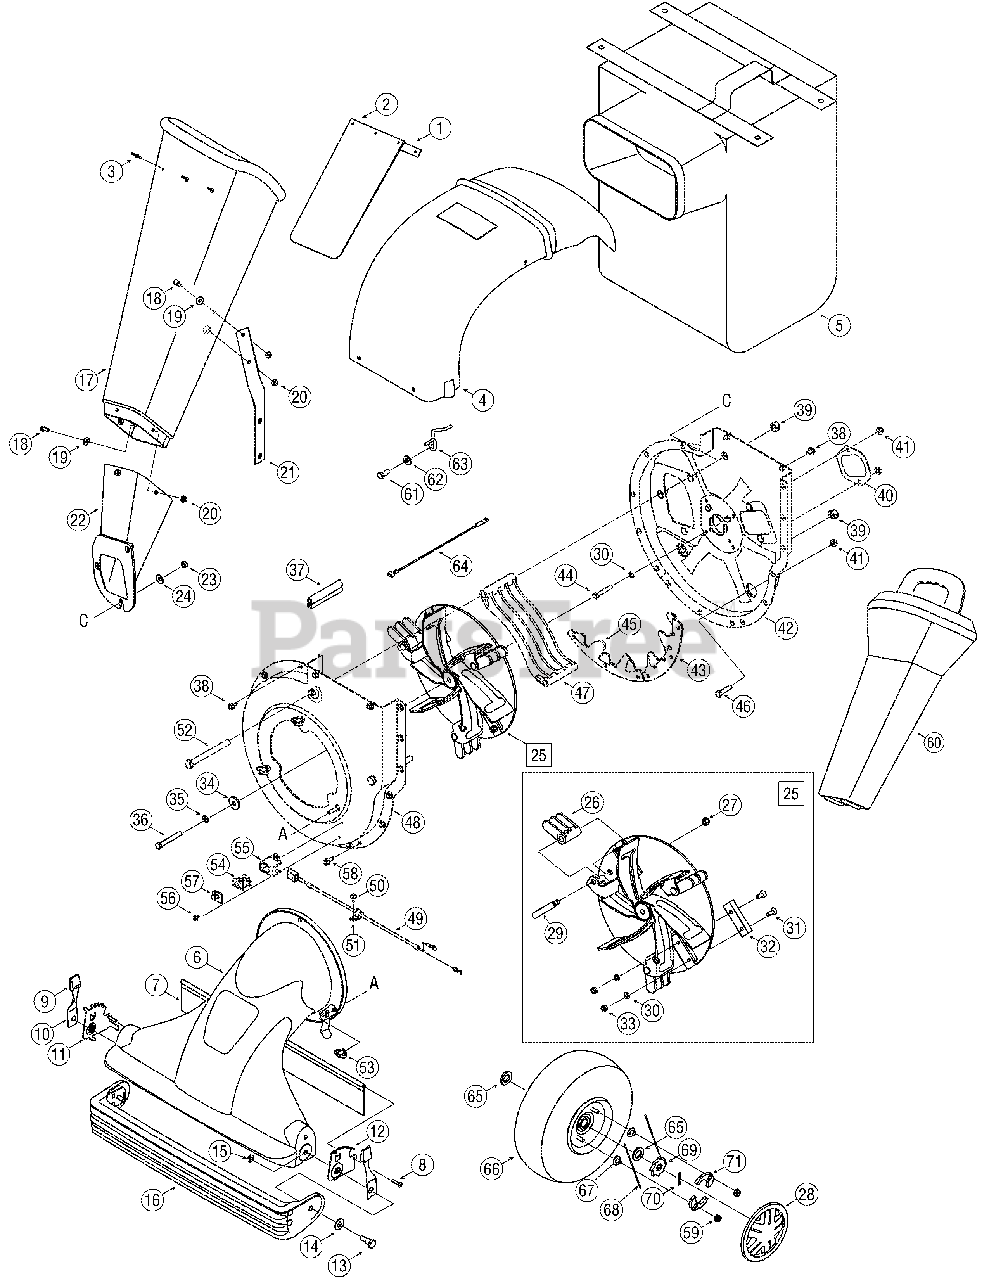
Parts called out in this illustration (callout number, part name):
1	Chute Flap Strip
2	Chute Flap
3	Pop Rivet
4	Discharge Chute
5	Bag
6	Nozzle Assembly
7	Nozzle Flap
9	Height Adjustment Knob
10	Spring Lever
13	Shoulder Screw
14	Flat Washer.510 x 1.12 x.060
15	Hex Flange Lock Nut 3/8-16
16	Door Assembly
17	Chipper Chute
18	Hex Cap Screw 1/4-20 x.620
19	Flat Washer.28 ID x.74 OD
20	Hex Lock Nut 1/4-20
24	Belleville Washer,.340ID x.872OD
25	Impeller Assembly: Complete
26	Flail Blade
27	Jam Lock Nut, 3/8-16
29	Shoulder Pin, .5 x 2.625
30	Lock Washer 5/16
31	Cap Screw 5/16-24 x 1.0
32	Chipper Blade
33	Hex Lock Nut 5/16-24
34	Flat Washer.406 x 1/1/4
35	Lock Washer 3/8
36	Hex Cap Screw 3/8-24 x 2.75
37	Rubber Seal
38	Hex Washer Screw 5/16-18
39	Hex Lock Nut 1/2-13
41	Hex Flange Lock Nut 5/16-18
44	Hex Cap Screw 5/16-18 x 2
46	Hex Cap Screw 5/16-18 x.75
47	Discharge Screen
49	Wire Harness
50	TT Screw 1/4-14 x 0.625"
52	Hex Cap Screw 1/2-13 x 5.0
53	Knob 5/16-18
54	Switch
55	Safety Switch Mounting Cover
56	Hex Washer Screw
57	Switch Cover
58	LD Screw 5/16-18 x 0.75"
59	Hex Flanged Lock Nut 1/4-20
60	Tamper Plug
61	Hex Cap Screw 5/16-24 x.75
62	Flat Washer.344 x.75 x.12
63	Belt Keeper
64	Adapter Harness Assembly
65	Flat Washer 5/8 ID x 1.0 OD
66	Wheel Complete 10 x 4 x 4
67	Hex Nut 1/4-20
68	Plastic Spring Ratchet
69	Wheel Ratchet 1.62 OD x.5 serr
70	Cotter Pin
71	Pawl LH.345 ID
71	Pawl RH.345 ID
